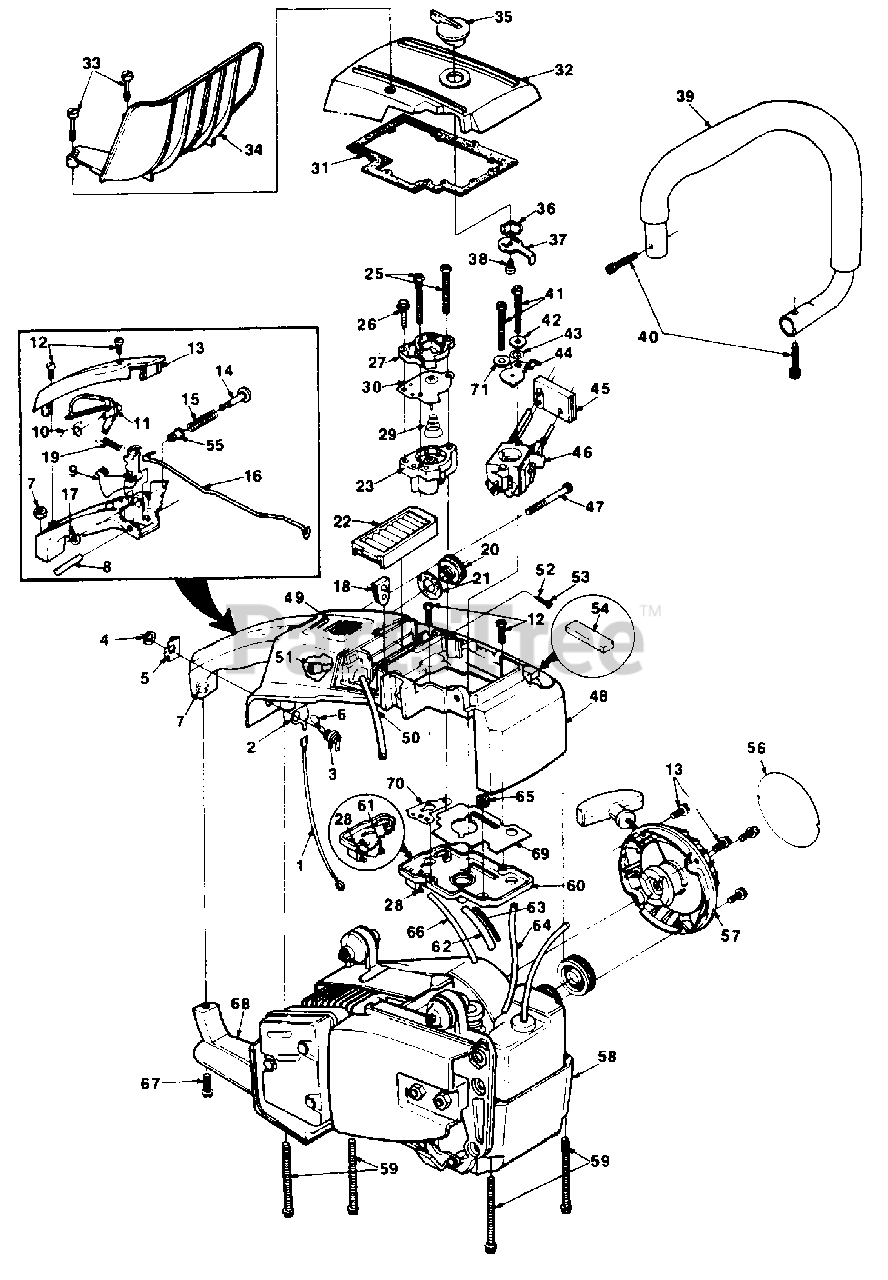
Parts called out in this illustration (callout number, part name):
1	LEAD- Electrical
2	CONTACT- Ground
3	SWITCH- Grounding
4	NUT- Switch
5	PLATE- Ignition (Run-Stop)
6	SLEEVE- Grounding switch
7	NUT- Locking hex (10-24)
8	PIN- Groove
9	TRIGGER- Throttle
10	SPRING- Torsional
11	THROTTLE- Interlock
12	SCREW- Hex hd. (8-32 x 1/2)
13	HANDLE- Cover
14	PIN- Throttle lock
15	SPRING- Compression
16	ROD- Throttle
17	RING- Retaining
18	GROMMET
19	SPRING- Extension
20	CAP- Oil
21	GASKET
22	FILTER ELEMENT- Air
23	PUMP Oil
25	SCREW- Hex hd. (8-32 x 2)
26	SCREW- Thd. forming (8-16 x 5/8)
27	COVER- Oil pump
28	FITTING- Tube
29	SPRING- Helicoil
30	DIAPHRAGM & PLUNGER
31	GASKET- Air filter cover
32	COVER- Air filter
33	SCREW- Self retaining (330 only)
34	GUARD- Hand (330 only)
35	BUTTON- Choke
36	WASHER- Wave
37	LEVER- Choke
38	SCREW- Pan taptite (8-32 x 5/16)
39	HANDLE BAR- Flush cut
40	SCREW Cap socket hd. (10-24 x 1)
41	SCREW- Mach. hex. hd. (10-32 x 1 7/8)
42	SPACER- Choke
43	WASHER- Wave
44	PLATE- Choke
45	GROMMET
46	CARBURETOR (Walbro WT-4)
47	SCREW- Cap socket hd. (10-24 x 1 3/4)
48	HOUSING- Engine
50	TUBING (after Lot #C309)
51	FINDER- Oil
52	VALVE- Duck bill
54	FILTER- Fuel tank valve
55	BUSHING- Flanged
56	DECAL- Starter housing
57	HOUSING- Starter
58	HOUSING- Engine (bottom)
59	SCREW- Hex hd. (10-24 x 2.5000)
60	PLATE- Carburetor chamber
61	FITTING- Tube (L)
62	TUBING- 2" (pulse line)
63	SPRING- Pulse line (inside)
64	TUBING- 5 1/4" (pulse line)
65	GROMMET
66	TUBING-3" (Oil Deliver)
67	SCREW- Sems hex hd. (10-24 x 3/4)
68	BRACE- handle
69	GASKET Carburetor
70	GASKET- Oil pump
71	SPACER- Flanged
